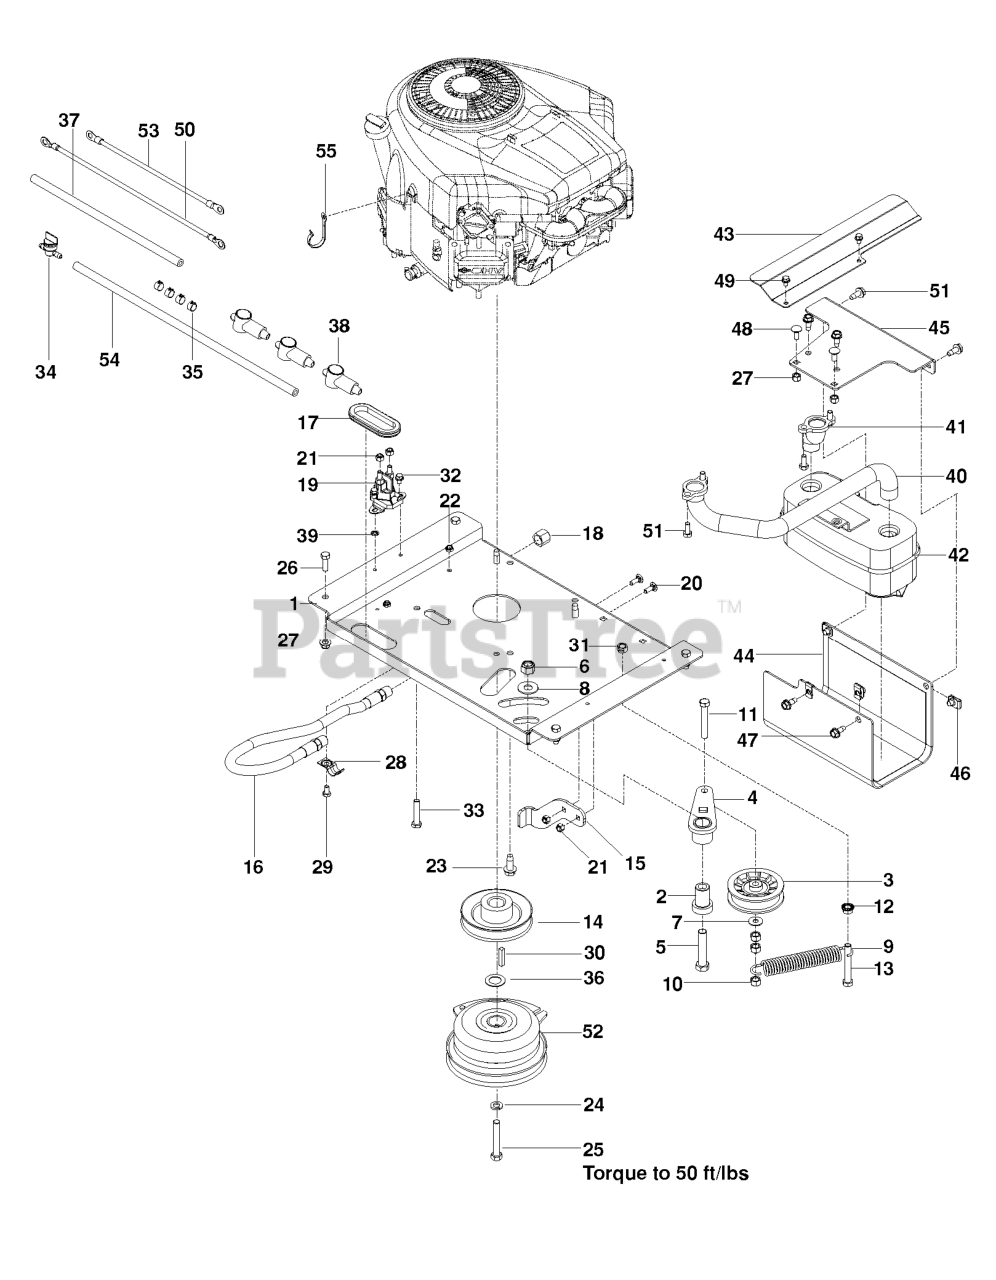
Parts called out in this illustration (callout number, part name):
1	PLATE, ENGINE
2	IDLER SPINDLE
3	PULLEY, IDLER RAKE & ZTR
4	RP.IDLER ARM WELDMENT
5	HEX SCREW 1/2-13 X 2.5" GR 5
6	NUT 1/2-13 HEX NYLOC ZD
7	WASHER 5/16 FLAT
8	WASHER 1/2 FLAT
10	NUT 3/8-16 NYLOC
11	HCS 3/8-16 X 2-1/2 TPBLT
12	NUT 3/8C WHIZ
13	SCREW 3/8C X 2 3/4 HEX CAP
15	TIE DOWN, CLUTCH
16	DRAIN, OIL
20	RHSNB 1/4C X 3/4
21	NUT.1/4-20.HEX.NYLOC.ZD
22	JAM NUT 1/4C (2 2 PW01)
23	HHFS 3/8-16 X 1.0 THD FORMING
24	WASHER 7/16 LOCK
25	BOLT 7/16F X 2 1/2
26	HCS 5/16C X 1
27	5/16-18 NYLOC FLANGE NUT
29	HCS 1/4-20.
30	KEY, 1/4 SQ X 1 1/4
31	NUT 3/8C CENTERBLOCK
32	HWST 1/4C X 3/8
33	HCS 5/16C X 1 3/4
34	FUEL VALVE
35	HOSE CLAMP
36	WASHER, 1.025 ID X 1.64
37	FUEL LINE 13"
39	WASHER 1/4 INT TOOTH
40	MANIFOLD, FT
41	MANIFOLD, RR
42	MUFFLER ASM TWIN
43	SHIELD, HEAT
44	GUARD, MUFFLER
45	MOUNT MUFFLER BLACK
46	U-CLIP 5/16-18 NUT RETAINER
47	BOLT 5/16-18 X 3/4
48	BOLT 5/16C X 3/4" CARRIAGE
49	HWST 1/4C X 3/8
50	BATTERY GROUND CABLE
51	HCS 5/16C X 3/4
52	CLUTCH, 125 FT/LB
53	CABLE, POSITIVE
54	FUEL LINE 30"
